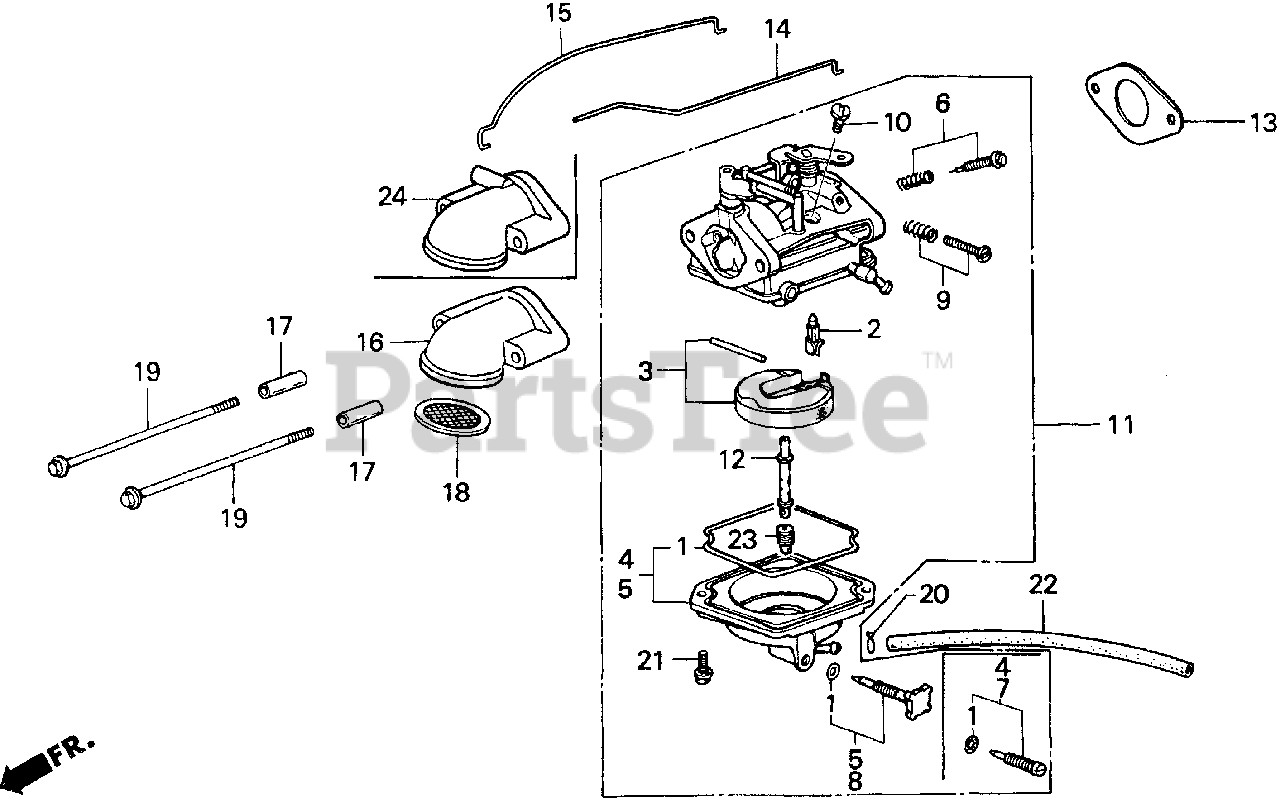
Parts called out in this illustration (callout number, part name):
1	GASKET SET
2	VALVE SET, FLOAT
3	FLOAT SET
5	CHAMBER SET, FLOAT
6	SCREW SET A
8	SCREW SET, DRAIN
9	SCREW SET B (N/A: SEE ASSEMBLY)
10	SCREW, PLUG
11	CARBURETOR ASSY. (NOT AVAILABLE)
12	NOZZLE, MAIN (N/A: SEE ASSEMBLY)
13	GASKET, CARBURETOR
14	ROD, THROTTLE
15	ROD, CHOKE
16	GUIDE, AIR (NOT AVAILABLE)
17	COLLAR, DISTANCE
18	TRAP, FLAME
19	BOLT, FLANGE (6X97)
20	CLIP B7, TUBE
21	SCREW-WASHER (4X12)
22	BULK HOSE, FUEL (3.5X3000) (3.5X140)
23	JET, MAIN (#72)
23	JET, MAIN (#78)
23	JET, MAIN (#80)
23	JET, MAIN (#82)
23	JET, MAIN (#85)
23	JET, MAIN (#88)
